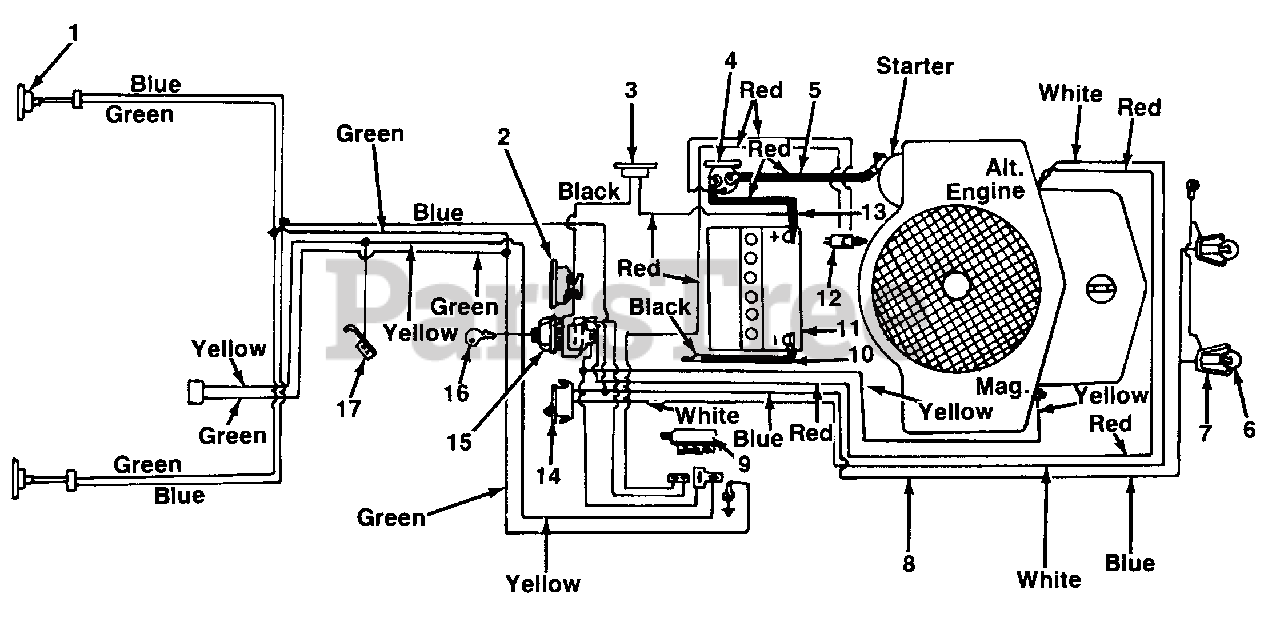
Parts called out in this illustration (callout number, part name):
1	Taillight
2	Ammeter
3	Circuit Breaker
4	Solenoid
5	Wire
6	Bulb Headlight
7	Socket Headlight
8	Wire Harness
9	Safety Switch
10	6 Ga. Black Wire
11	12V Battery
12	Safety Switch
14	Headlight Switch
15	Ignition Switch
16	Ignition Key
17	Spring Switch Reverse
